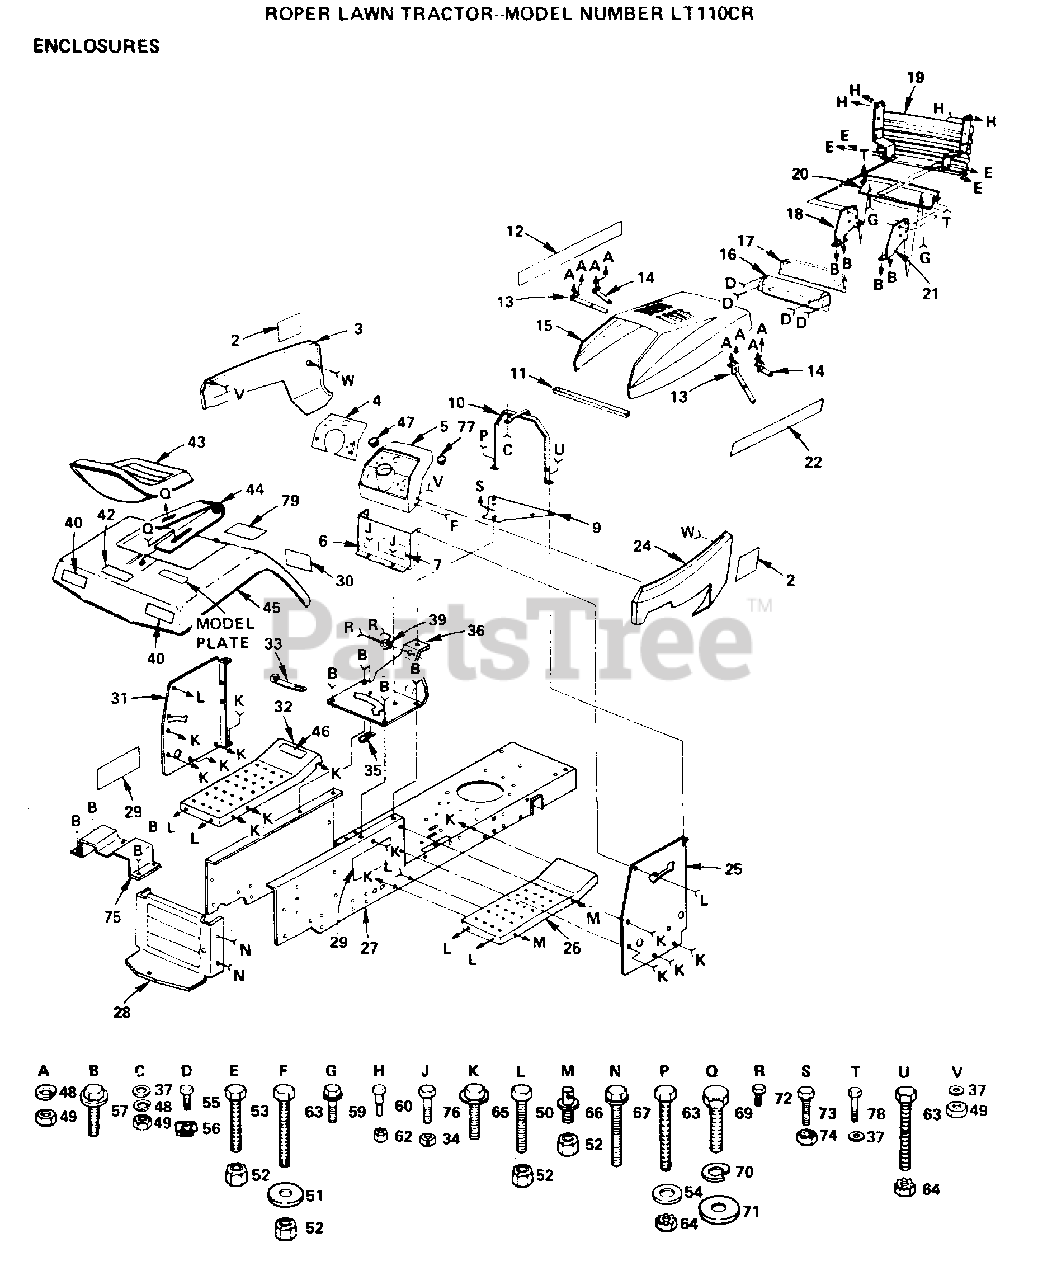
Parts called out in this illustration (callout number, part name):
5	DASHBOARD LT
6	DASH ASSY LT
7	DECAL, INSTRUCTION
10	SUPPORT ASSY LT
11	FOAM-STRIP LT
17	LENS LT
18	SUPPORT-GRILL LT
30	DECAL-CAUTION
33	WIRE TIE
35	CLIP T
37	WASHER PM
44	SPRING - SEAT
47	PLUG-DASH T
51	WASHER
53	BOLT
54	WASHER
56	"""J"" FASTENER LT"
57	SCREW
59	SCREW
60	BOLT T
64	NUT
65	SCREW LT
66	PIN SUSPENS. LTV
67	SCREW GTV
69	BOLT
71	WASHER
73	BOLT
75	BRACKET ASSY - FENDER
77	PLUG BUTTON T
78	SCREW HEX CRT
